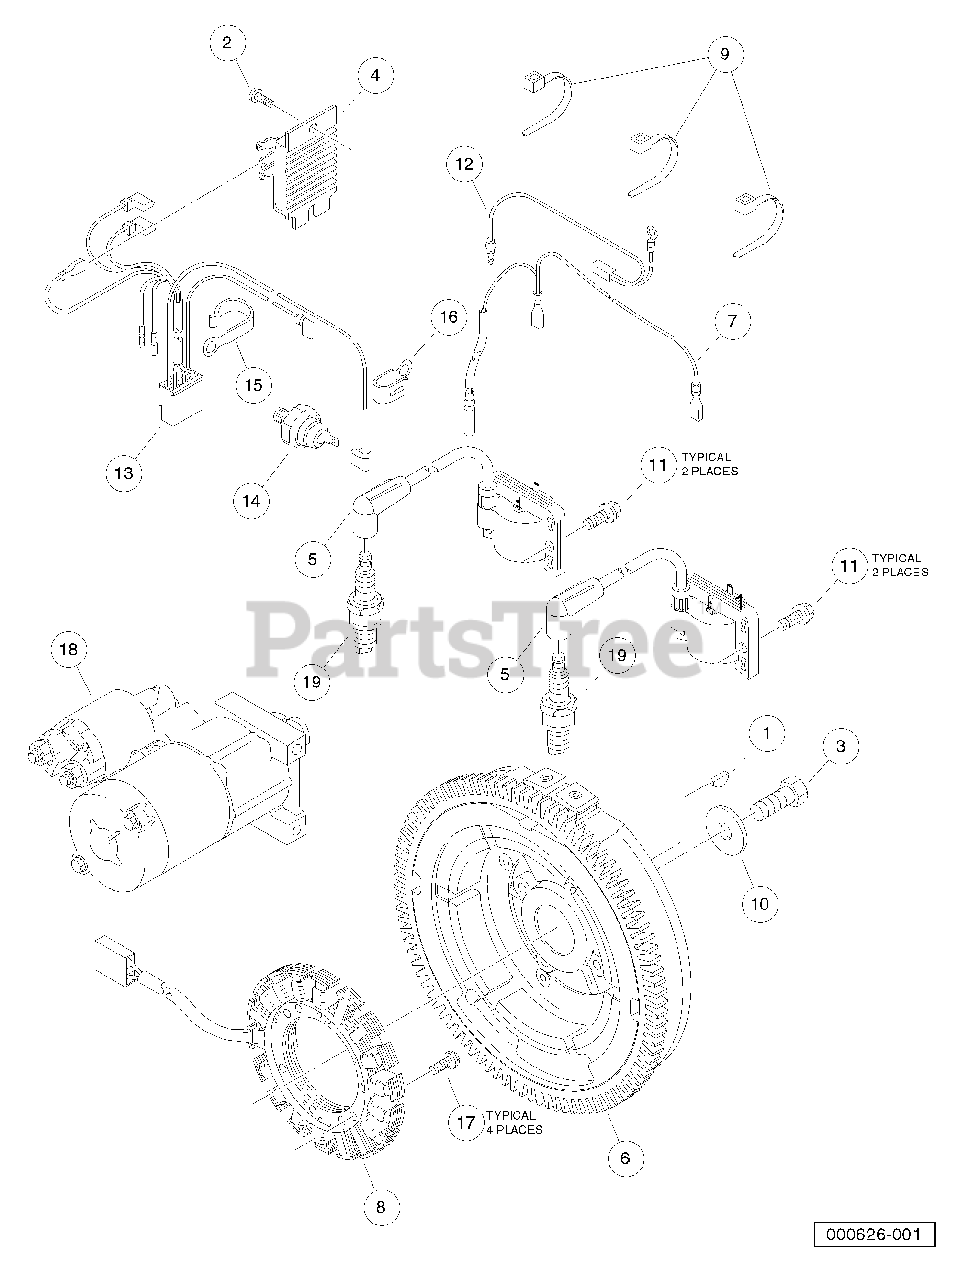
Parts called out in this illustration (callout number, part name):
3	Bolt, Flg, M12 X 1.25 X 30
4	Regulator, Voltage, Fh
5	Coil, Assy, Ignition, Fh
6	Flywheel, Assy, Fh
7	Harness, Regulator, Fh
8	Coil, Charging, Fh
9	Band, Harness, Fh
10	Washer, Flywheel, Fh
11	Bolt, Flanged, M6 X 20, Kaw
12	Harness, Ignition, Fh
13	Harness, Engine, Main, Fh
14	Switch, Oil Pressure, Fh
15	Clamp, Harness, Large, Fh
16	Clamp, Harness, Small, Fh
17	Screw, Pan, Coil Mount, Fh
18	Starter, Electric, FH680D
19	Spark Plug, BPR2ES
